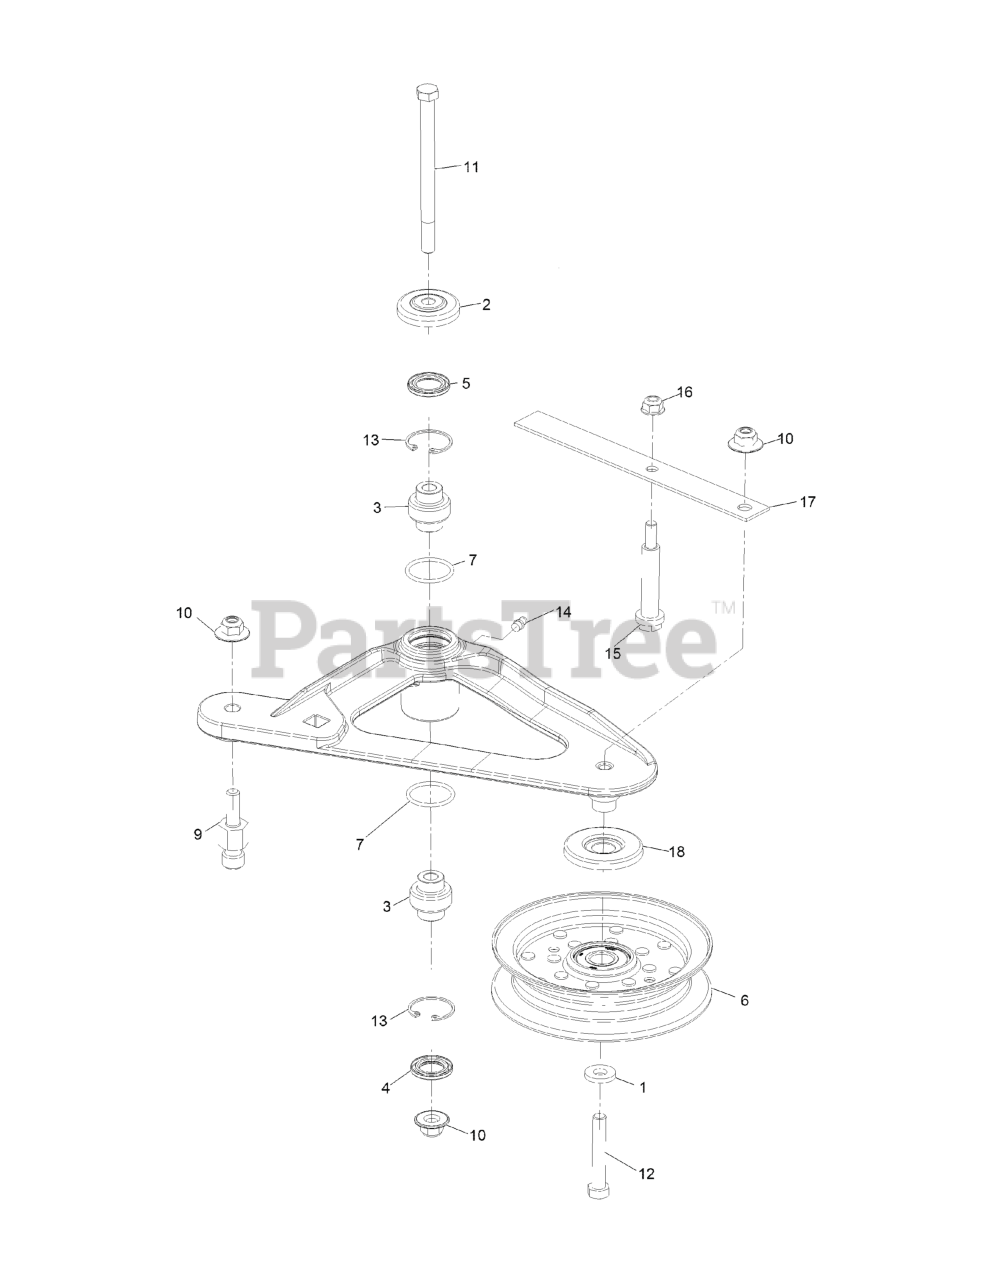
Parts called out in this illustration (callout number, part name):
2	GUARD-TOP
3	BEARING-SPHERICAL
4	SEAL-LIP, DOUBLE
5	SEAL-LIP, SINGLE
6	IDLER-PULLEY, FLAT
9	PIN-SPRING, ANCHOR
10	Nut-Nyloc 3/8-16 Flg
11	SCREW-SHOULDER, HH
12	SCREW-HH
13	RING-SNAP
14	FITTING-GREASE
15	BOLT-SHOULDER
16	NUT-HF, NI
17	SPRING-BELT
18	SHIELD-GUARD, DUST
